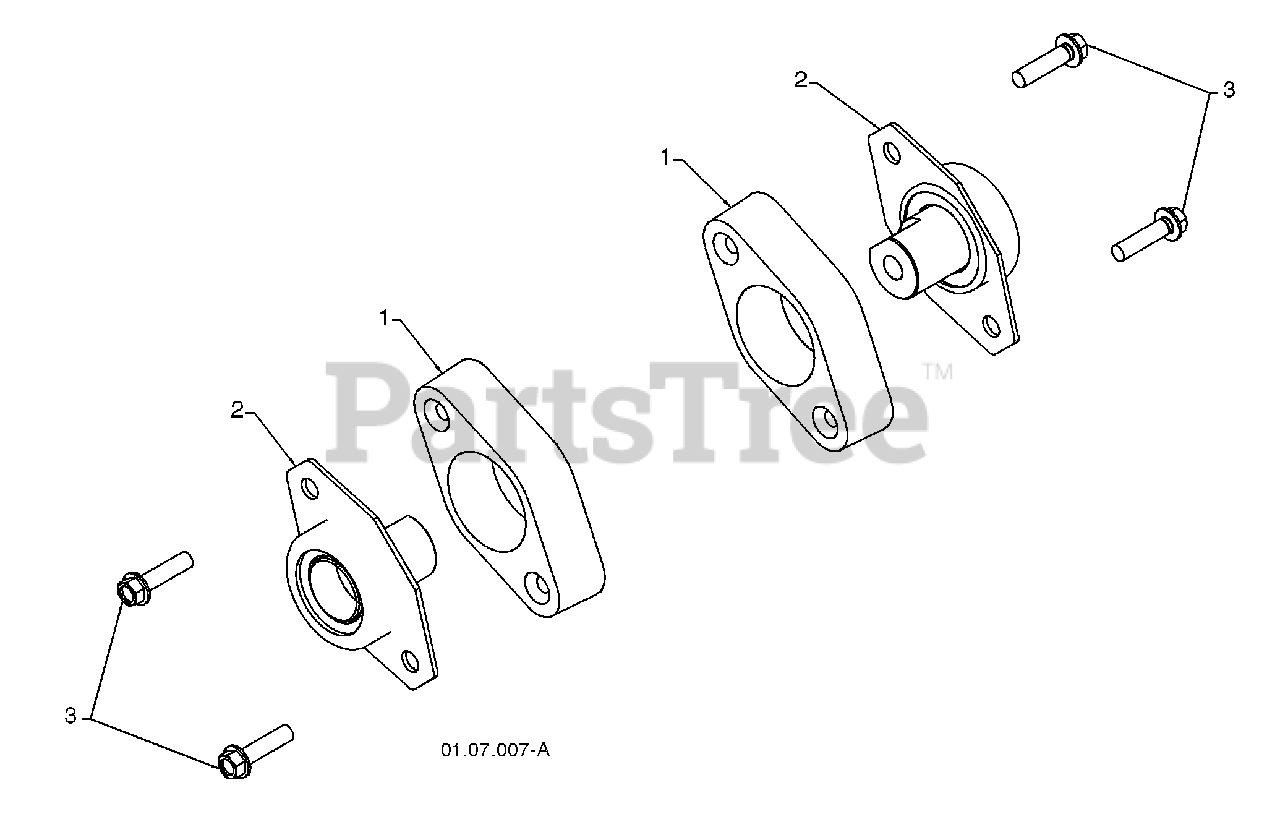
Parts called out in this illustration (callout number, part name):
1	PLASTIC RETAINER
2	AUGER BALL BEARING
3	SCREW 5/16-18 X 1.00
